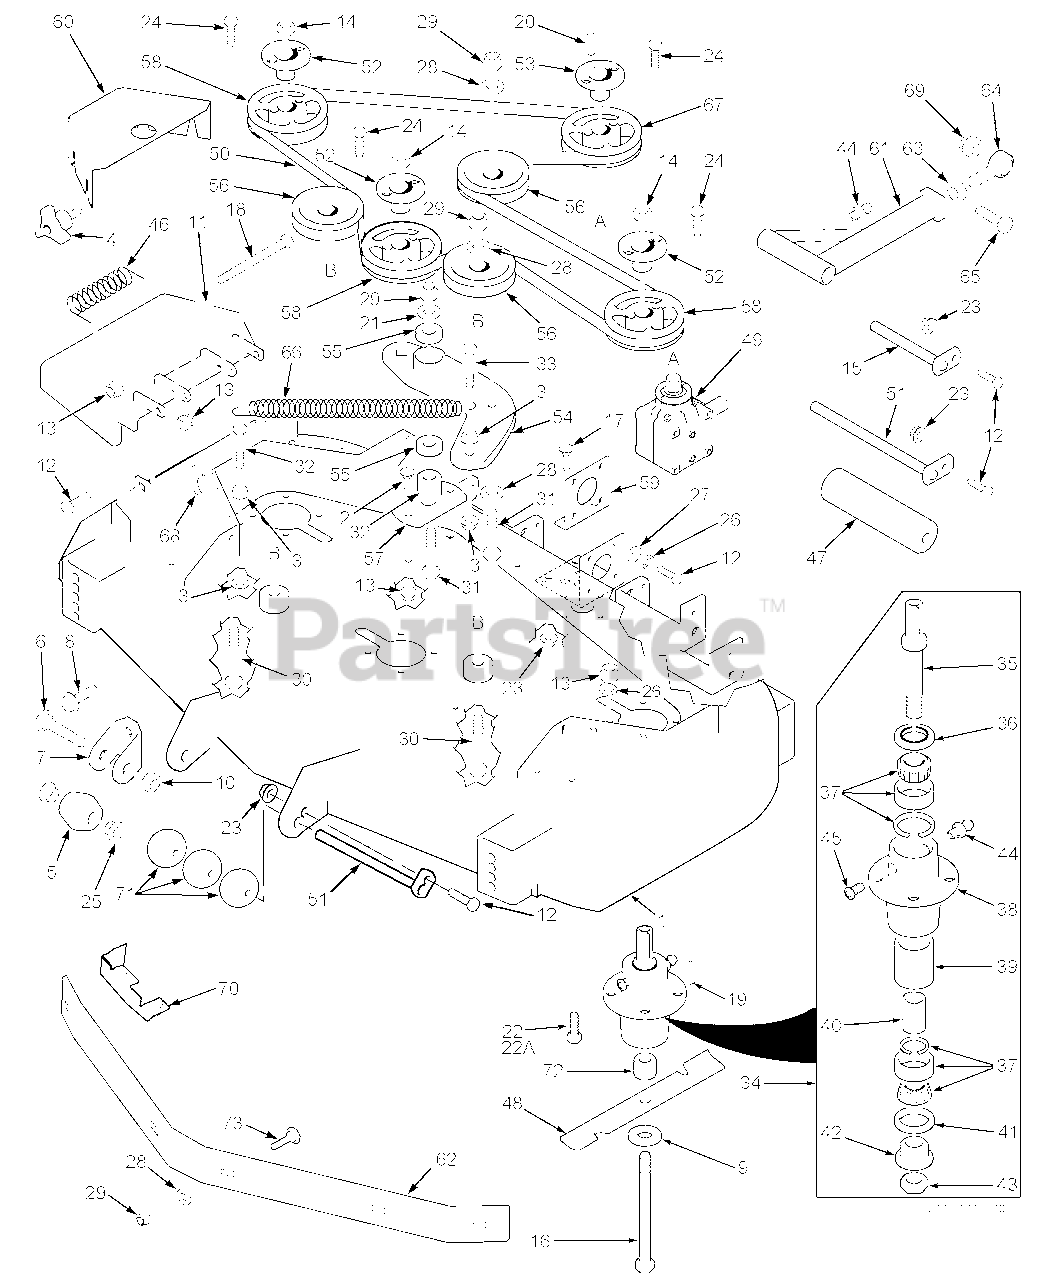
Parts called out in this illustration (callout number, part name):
1	Cutter Deck, 72" Advantage
2	Bolt, Carriage 5/16-18 x 1"
3	Nut, Hex Serrated Flange 3/8-16
4	Wing Nut, 3/8-16
5	Anti-Scalp Wheel
6	Bolt, Carriage 3/8-16 x 4"
7	Anti-Scalp Wheel Bracket
8	Bolt, Hex Serrated Flange 3/8-16 x 1"
9	Flatwasher, 5/8" Hardened
10	Locknut, 3/8-16 Center Lock
11	Discharge Chute, 61" & 72" Adv.
12	Bolt, Hex Head 5/16-18 x 1.75" (Front)
13	Nut, Hex Elastic Stop 5/16-18 Grade 8
14	Nut, 5/8-11 UNC
15	Push Arm Shaft
16	Bolt, Hex Head 5/8-11 x 9.50"
17	Bolt, Carriage 5/16-18 x .75"
18	Bolt, Hex Head 5/16-18 x 4.75"
19	Key, 1/4 x 1/4 x 2"
20	Key, 1/4 x 1/4 x 1.25"
21	Flatwasher,3/8-.39 x .938 x .105 HD
22	Bolt, Hex Head 5/16-18 x 1-3/4"
23	Nut, Hex Serrated Flange 5/16-18
24	Bolt, Hex Head 1/4-20 x 1" Grade 8
25	Bushing, .376 I.D. Oilite
26	Lockwasher, 5/16"
27	Flatwasher, 5/16" (.375 x .875 x .083)
28	Flatwasher, 3/8" (.391 x .938 x .105)
29	Nut, Hex Elastic Stop 3/8-16
30	Bolt, Hex Head 3/8-16 x 3.25"
31	Bolt, Hex Head 3/8-16 x 2.50"
32	Pivot, Idler - Short
33	Bolt, Hex Head 3/8-16 x 1.50" Grade 8
34	Spindle Assembly
35	Spindle Shaft
36	Seal, Top
37	Bearing Assembly
38	Spindle Housing
39	Spacer, Outside
40	Spacer, Inside
41	Seal, Bottom
42	Spindle Bushing, Bottom
43	Nut, Special 1 - 1/16-18
44	Grease Fitting
45	Relief Fitting, Tapered Spindle
46	Spring, Discharge Chute
47	Guide, Roller
48	Cutter Blade, 24.5" 72"
49	Gearbox Assembly, Deck Drive
50	Belt, Cutter Deck Drive, 72"
51	Roller Shaft
52	Tapered Hub, 1-1/8" Bore
53	Tapered Hub, 1" Bore
54	Idler Arm, Cutter Deck
55	Bearings, Ball
56	Pulley, Idler
57	Base, Idler Pivot
58	Pulley, 6.95 O.D. - 72"
59	Mounting Plate, Gearbox
60	Belt Cover, LH - 72"
61	Pusharm
62	Baffle, Custom Cut 72A
63	Nut, Hex Head 5/8-18 UNF
64	Rod End, 5/8" Male RH Thread
65	Bolt, Hex Head 5/8-11 x 4-1/2"
66	Spring, Cutter Deck
67	Pulley, 6.35 O.D. - 72"
68	U-Nut, 3/8-16
69	Nut, Hex Elastic Stop 5/8-11
70	Discharge Baffle 72"
71	Wheel, Anti-Scalp
72	Spacer, Spindle Bottom
73	Bolt, Carriage 3/8-16 x 1"
04001.11	Bolt, Hex Head 5/16-18 x 1.50" (Rear)
